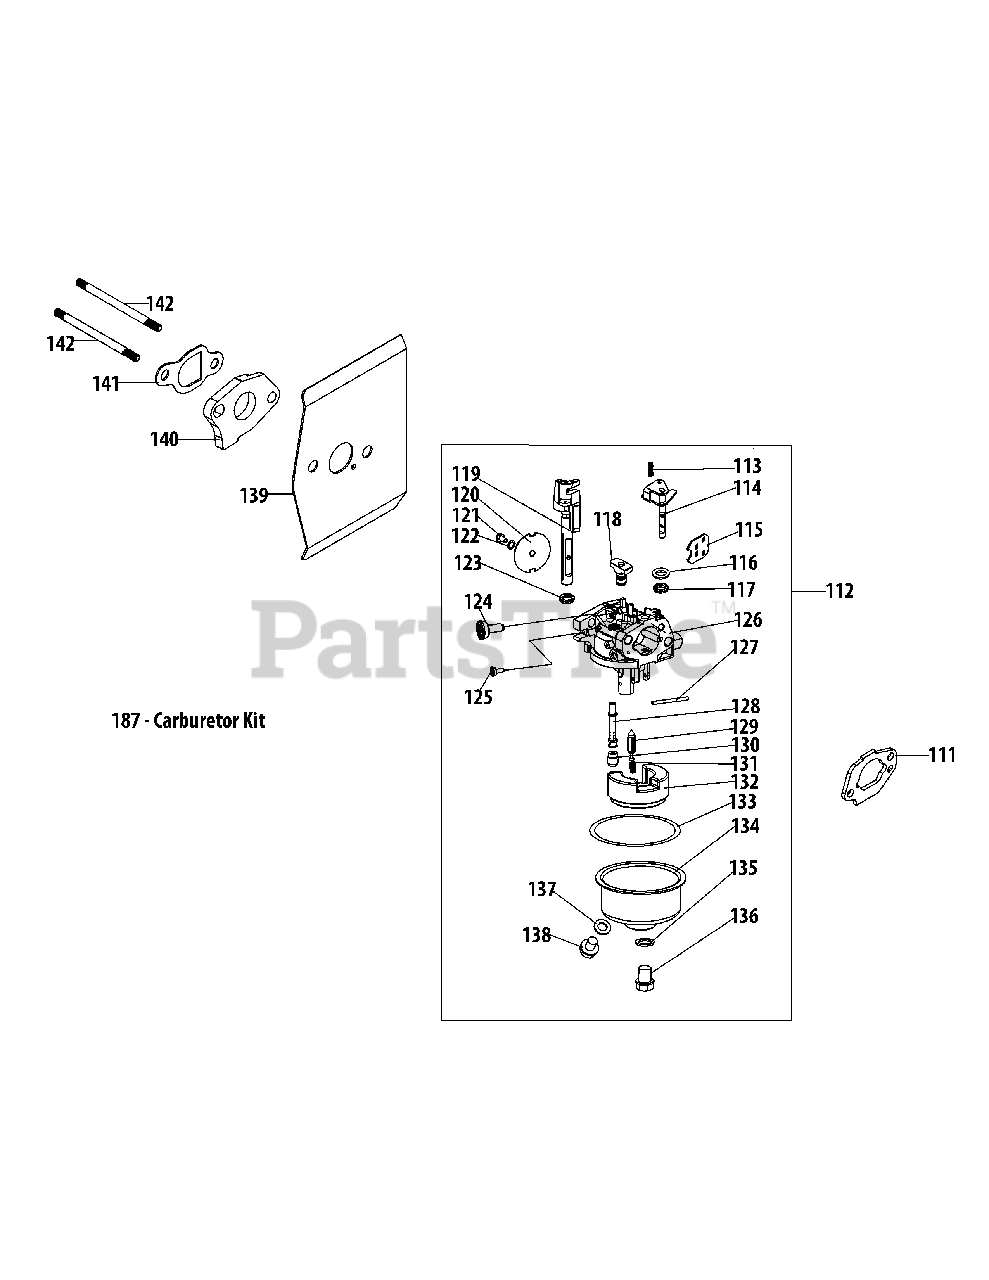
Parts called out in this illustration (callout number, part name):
111	Carburetor Gasket Plate
112	Carburetor Assembly
113	Detent Spring
114	Choke Shaft
115	Choke Plate
116	Choke Shaft Washer
117	Choke Shaft Fiber O-Ring
118	Idle Jet Assembly
119	Throttle Shaft
120	Throttle Plate
121	Screw M3X6 Throttle Plate
122	Throttle Plate Lock Washer
123	Throttle Shaft Fiber O-Ring
124	Idle Speed Adjusting Screw
125	Idle Mixture Screw
126	Carburetor Body
127	Float Pin
128	Emulsion Tube
129	Needle Valve
130	Main Jet
131	Needle Valve Spring
132	Float
133	Fuel Bowl O-Ring
134	Fuel Bowl
135	Fuel Bowl Gasket
136	Fuel Bowl Mounting Bolt
137	Fuel Drain Plug Gasket
138	Fuel Drain Plug
139	Carburetor Gasket
140	Carburetor Insulator
141	Carburetor Insulator Gasket
142	Carb Stud M6X92
187	Carburetor Kit - Major
